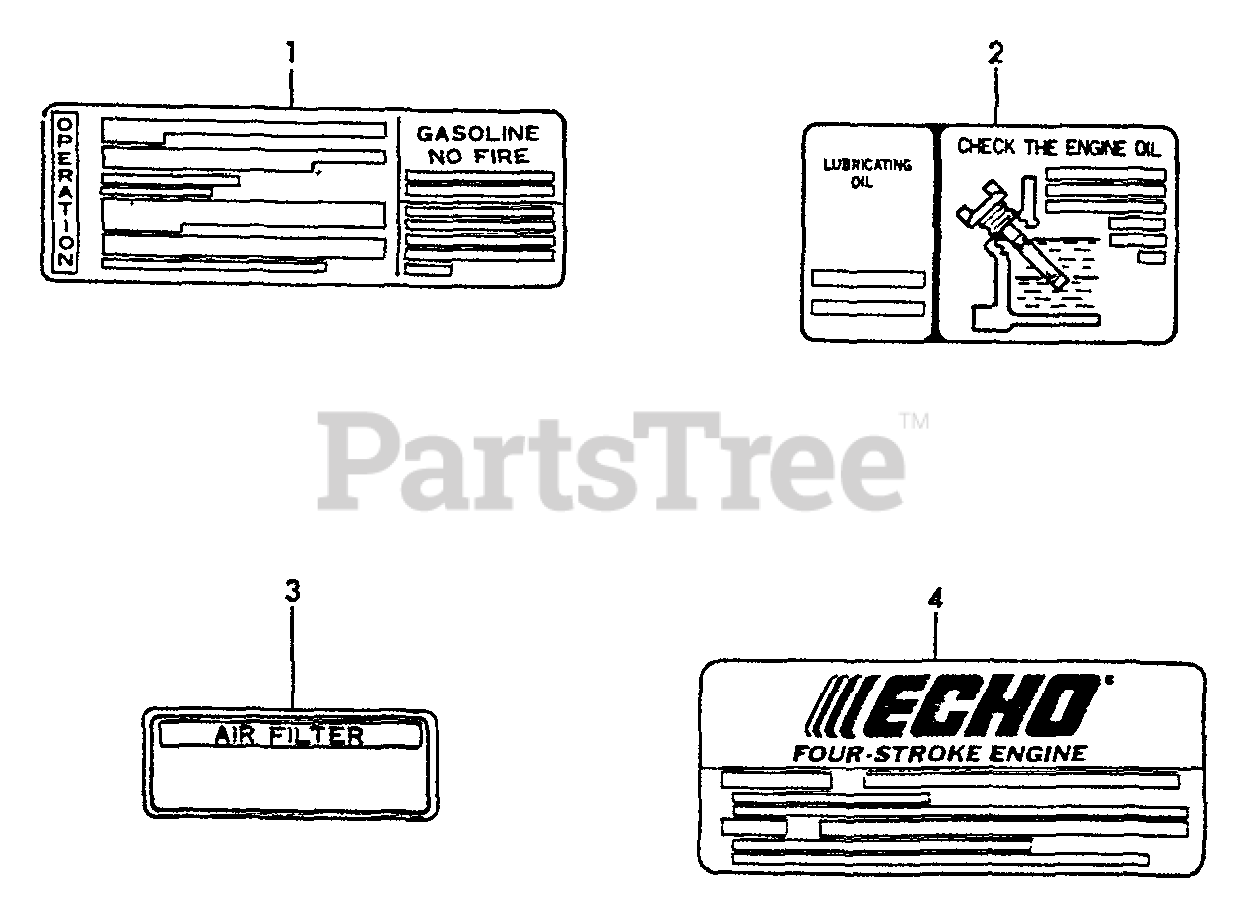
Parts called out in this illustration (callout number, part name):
1	LABEL, OPERATION
2	LABEL, OIL
3	LABEL - AIR FILTER
4	LABEL, ECHO
